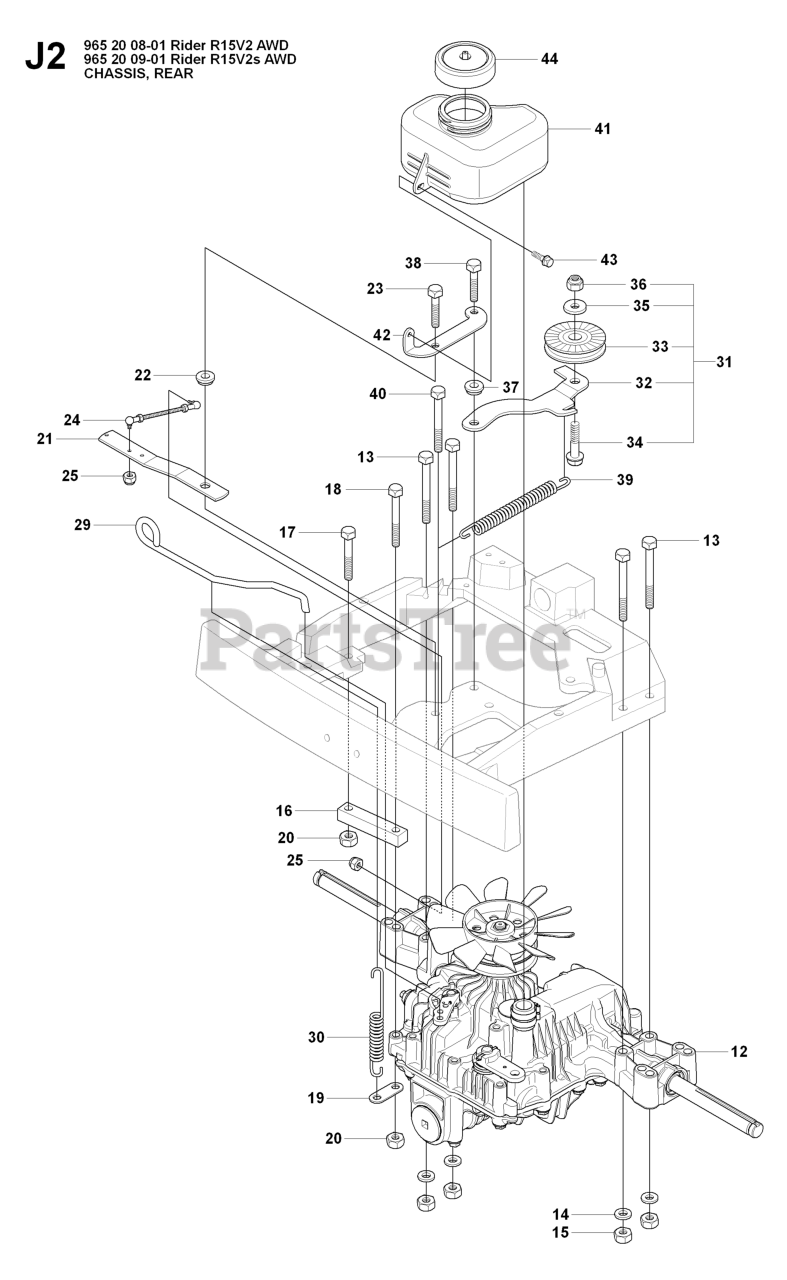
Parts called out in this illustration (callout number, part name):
12	HYDRAULMOTOR
14	WASHER BRB 8.4X17
15	NUT
20	NUT
22	WASHER
23	SCREW 8X20
25	LOCKNUT M5
32	TENSIONER
34	SCREW
36	LOCKNUT M8
37	WASHER
38	SCREW 8X20
